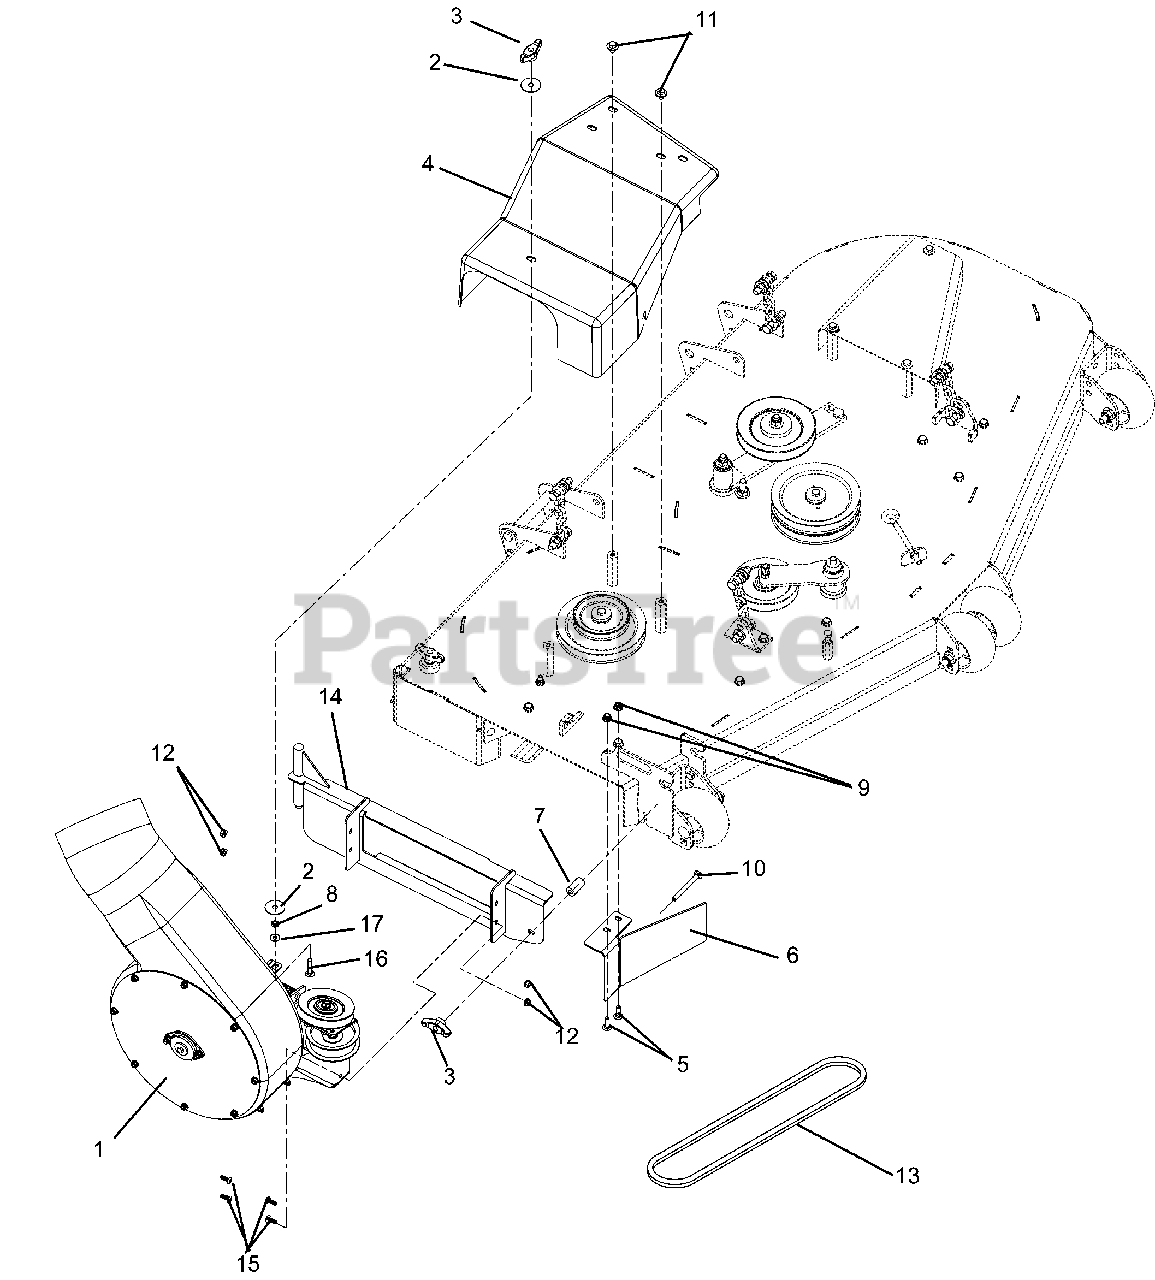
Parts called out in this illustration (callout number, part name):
1	Housing, Blower
2	Washer-Flat-Steel .38 x 1.50 x .062
3	Knob- Wing .312-18
4	Belt Cover (991037, 038, 039, 040, 041)
5	Bolt, Round Head Square Neck .31-18 x 1 Grade 5 (991038, 040, 041)
6	Baffle, 60"HD Bagger (991038, 040, 041)
7	Spacer, CZ-Head Bagger
8	Nut-Jam .312-18
9	Nut, .31-18 Nyloc Flange (991038, 040, 041)
10	Bolt, Round Head Square Neck .38-16 x 1.00
11	Knob, Wing Stud 5/16-18 x .75
12	Nut-Locking-Top-Flange .25-20
13	Belt, 4L 70.81 Raw (991038, 040, 041)
14	60" HD Bag Pump Mounting Bracket Weldment (991038, 040, 041)
15	Screw-Machine .25-20 x .75
16	Bolt-Round Head Square Neck .31-18 x 1.50
17	Washer, Flat Steel .312 x .734 x .065
